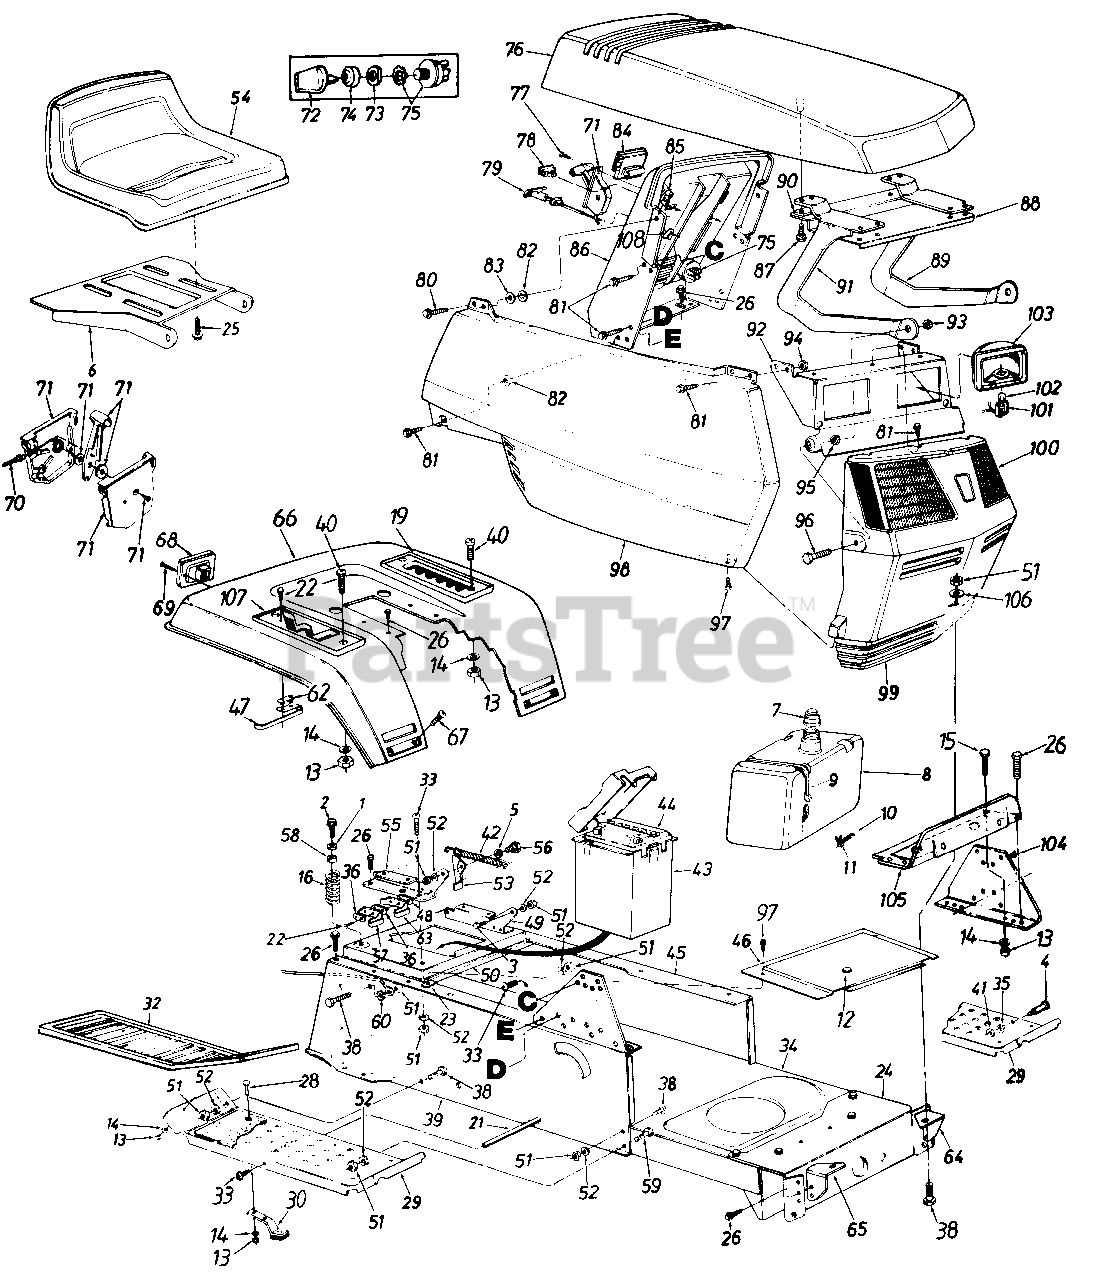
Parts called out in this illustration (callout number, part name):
1	Fl-Wash. .344" I.D. x .875"
2	Hex Wash. Hd. Tap Scr. 5/16-18 x 1.25" Lg.
3	Shld. Bolt .437" Dia. x .162
4	Shld. Bolt .50" Dia. x .84"
5	Spr-Wash. .445" I.D. x .75
6	Seat Pivot Bracket
7	Fuel Cap w/o Gasket
8	Fuel Tank
9	Tie Strap
10	Fuel Line
11	Hose Clamp
12	Snap Bushing
13	Hex Nut 1/4-20 Thd.
14	L-Wash. 1/4" I.D.
15	Hex Bolt 1/4-20 x .62" Lg.
16	Compression Spring
19	7-Speed Index Brkt.
21	Running Board Rod
22	Hex Wash. Hd. AB-Tap Scr. #8 x .50" Lg.
23	Speed Nut #10Z
24	Front Pivot Brkt.
25	Hex Tap Scr. 3/8-16 x .75"
26	Hex Wash. Hd. AB-Tap Scr. 5/16 x .75" Lg.
28	Carriage Bolt 1/4-20 x .62"
29	Running Board
30	Blade Brake Ass'y.
32	Rubber Foot Pad L.H.
33	Truss Mach. Scr. 5/16-18 x .75" Lg.
34	Lower Frame
35	L-Wash. 3/8" I.D.
36	Insulator Plate
38	Hex Bolt 5/16-18 x .75" Lg.
39	Upper Frame R.H.
40	Truss Mach. Scr. 1/4-20 x .75" Lg.
41	Hex Nut 3/8-16 Thd.
42	Extension Spring 5.31" Lg.
43	Battery Box w/Cover
44	12-V Battery
45	Upper Frame L.H.
46	Shift Cover
47	Reverse Safety Switch
48	Insulator Boss Plate
51	Hex Nut 5/16-18 Thd.
52	L-Wash. 5/16" I.D.
53	Seat Lift Brkt.
54	Seat
57	Spring Switch
58	Bushing
59	Truss Hd. Scr. 5/16-18 x 1.0" Lg.
60	External L-Wash. 5/16" I.D.
62	Insulator Nut Plate
63	Safety Switch (Seat)
64	Grille Mount Brkt. L.H.
65	Grille Mount Brkt. R.H.
66	Fender
67	Carriage Bolt 1/4-20 x .62" Lg.
68	Taillight
69	Truss Hd. AB-Tap Scr. #6 x .62" Lg.
70	Throttle Wire 26" Lg.
71	Throttle Control Box Ass'y.
72	Ignition Key
73	Ignition Switch Nut
74	Ignition Switch Cap
75	Ignition Switch
78	Light Switch
79	Choke Control 38" Lg.
80	Hex Wash. Hd. Tap Scr. 1/4 x.75" Lg.
81	Hex Tap Scr. 1/4-20 x .5" Lg.
82	Push Nut Fastener
83	Fl-Wash. .27" I.D. x .948"
84	Ammeter
85	Speed Nut 1/4-20 Thd.
86	Dash Panel
87	Hex Wash. Hd. B-Tap Scr. 1/4 x .62" Lg.
88	Hood Reinforcement
89	Hood Hinge L.H.
94	Hex L-Nut 1/4-20 Thd.
95	Hex Jam Nut 5/16-18 Thd.
96	Hex Bolt 5/16-18 x 7/8" Lg.
97	Truss Mach. B-Tap Scr. #10 x 5" Lg.
98	Side Cover R.H.
99	Grille
100	Lens L.H.
101	Twist Lock Lamp Socket
102	Lamp
103	Headlight Housing
104	Dash Support Brkt.
105	Gas Tank Support Brkt.
106	Fl-Wash. .34" I.D. x .68"
107	Forward/Reverse Index Brkt.
108	Choke Retainer
